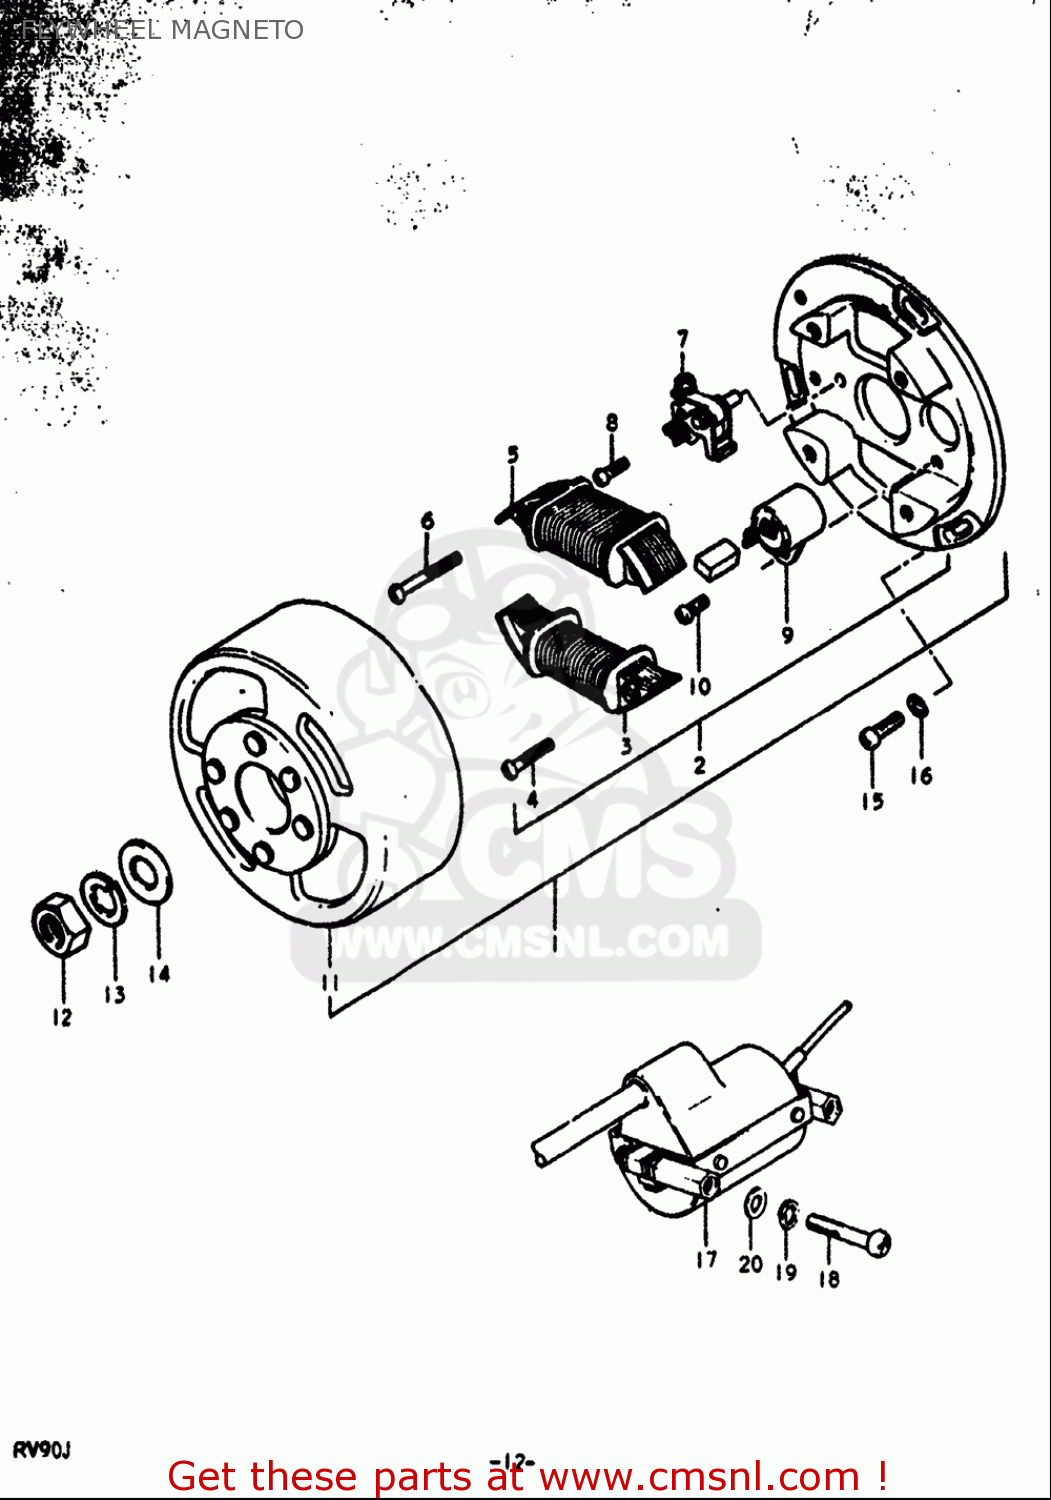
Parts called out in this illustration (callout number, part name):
4	SCREW
6	SCREW
7	POINT ASSY,CONTACT
8	.SCREW
9	CONDENSER
10	SCREW
12	NUT
13	WASHER,LOCK
14	WASHER
15	SCREW
16	WASHER
17	COIL ASSY,IGNITION
18	SCREW
19	WASHER,LOCK
20	WASHER
